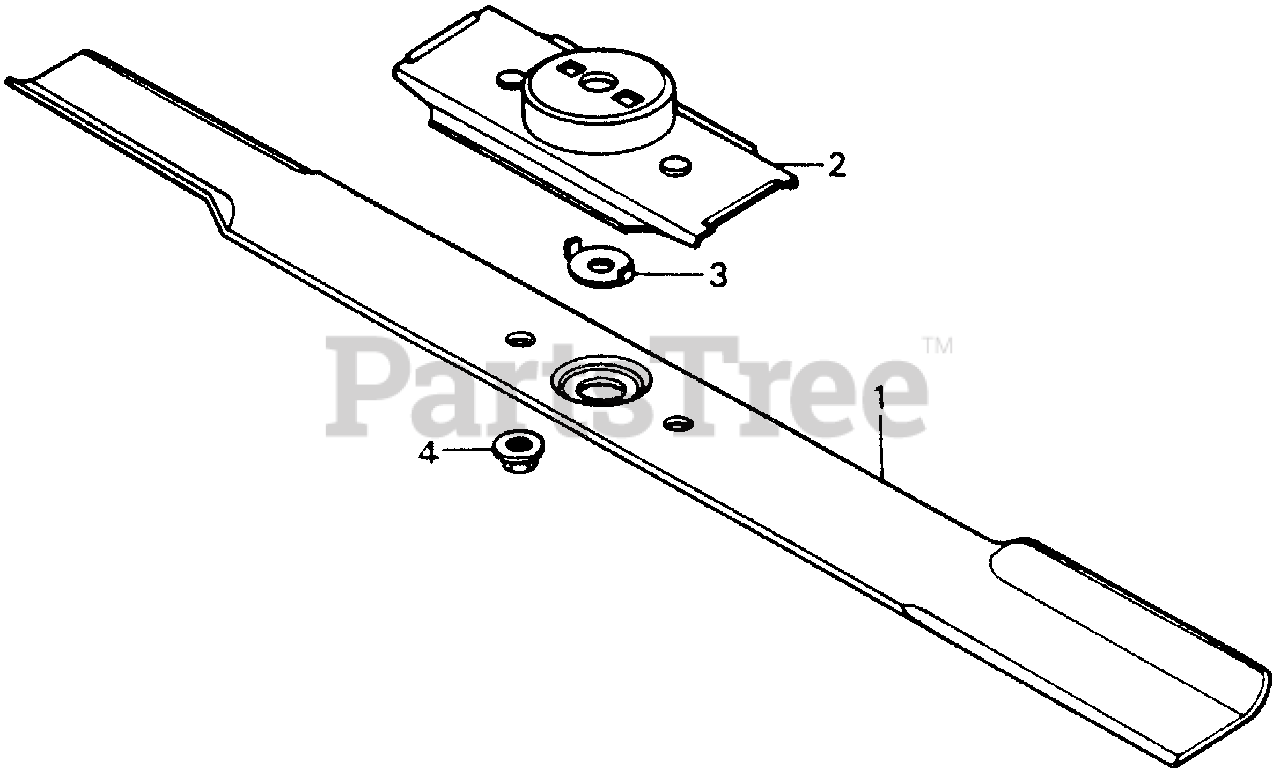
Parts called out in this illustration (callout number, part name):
1	BLADE, ROTARY
2	HOLDER, BLADE
3	WASHER, BLADE HOLDER
4	NUT, U (10MM) (FUSE RASHI)
